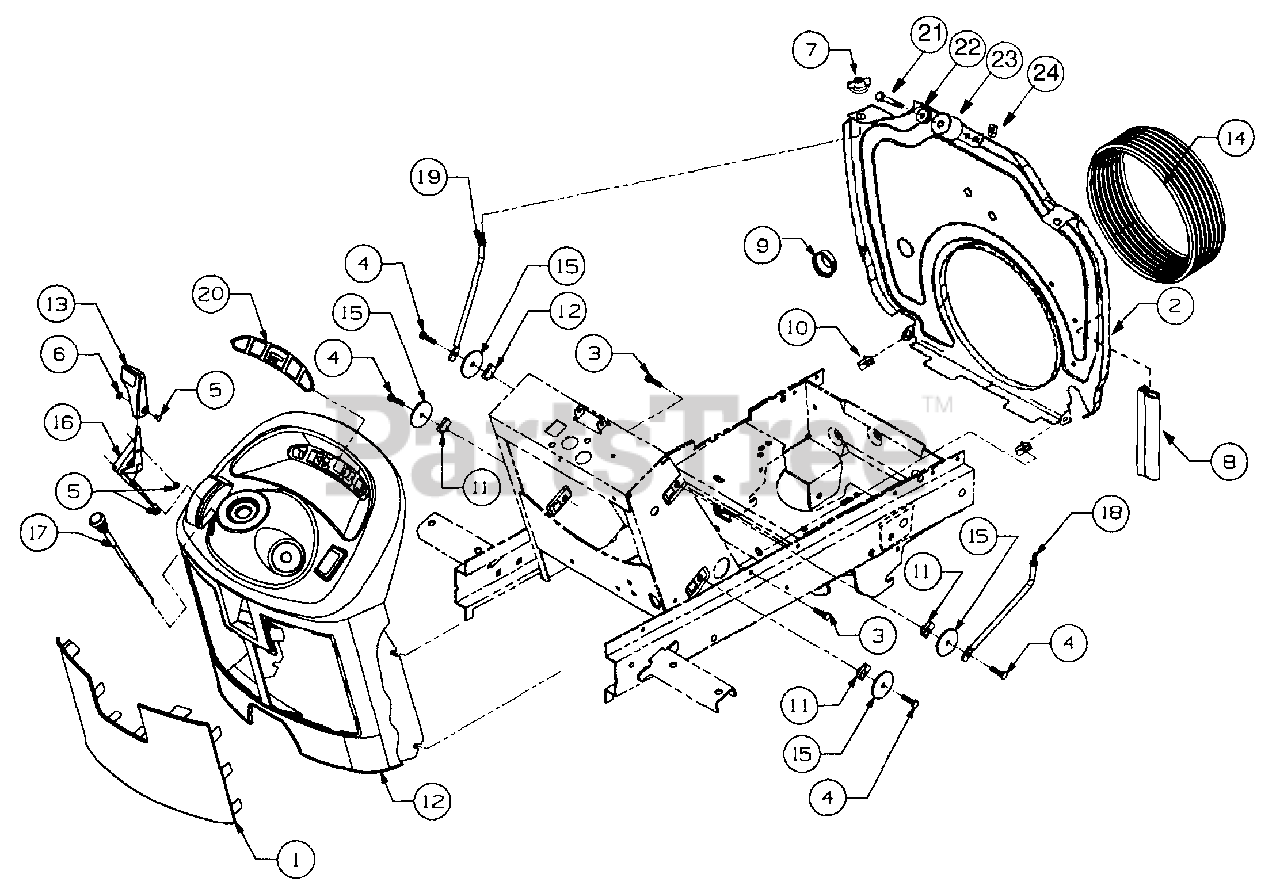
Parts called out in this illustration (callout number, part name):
2	Bulkhead, Lower
4	Screw, Hex Cap, 1/4-20 x 1.0
5	Screw, Cross Rec Truss Hd, #8-32 x.38
6	Nut, #8-32
7	Nut, Wing w/Bell Washer, 1/4-20
8	Seal, Push On Trim
9	Bushing, Snap, 7/8 ID
10	Nut, U-Type Speed, 1/4-20
11	Nut, U-Clip, 1/4-20
12	Panel Dash
13	Knob, Throttle
14	Boot, Intake
15	Washer, Flat, .285 x 1.75 x .10
16	Control, Throttle
17	Control, Choke
18	Rod, RH Mounting
19	Rod, LH Mounting
20	Label, Dash
21	Screw, Hex Cap, 1/4-20 x 1.75 GR5
22	Washer, Flat, .283 x .75 x .030
23	Roller, Hood Latch
24	Nut, Hex Sems, 1/4-20
